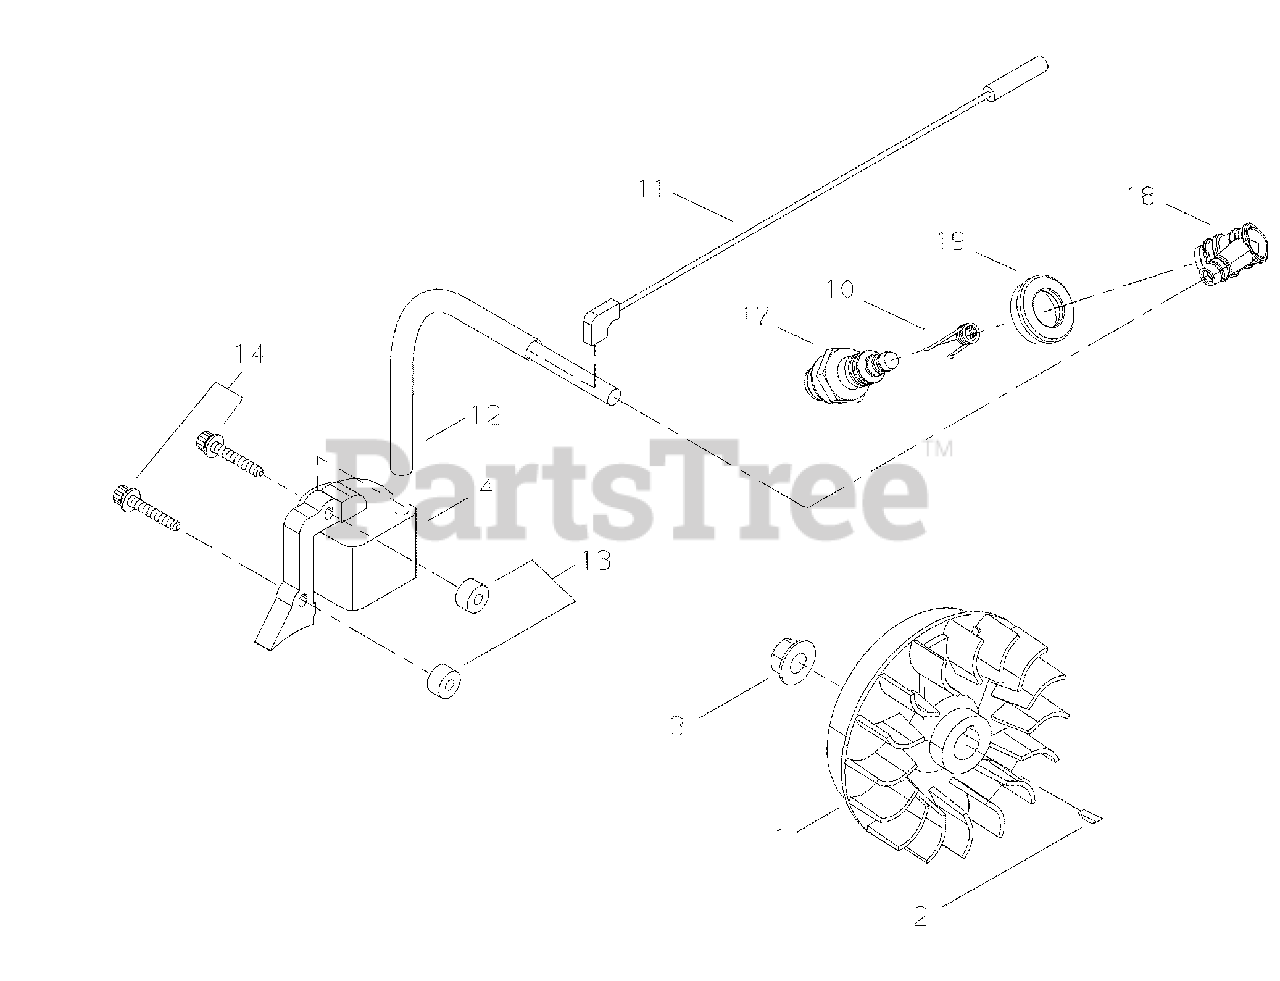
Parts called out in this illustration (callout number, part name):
1	FLYWHEEL
2	KEY, WOODRUFF 3×10
3	NUT M8
4	COIL, IGNITION
10	TERMINAL, SPARK PLUG
11	LEAD - IGNITION L= 215
12	TUBE, IGNITION COIL
13	INSULATOR 4.2×11×6
14	BOLT, ADHESIVE M4×20
17	SPARK PLUG - BPMR6A
18	CAP, SPARK PLUG
19	SEAL, SPARK PLUG
